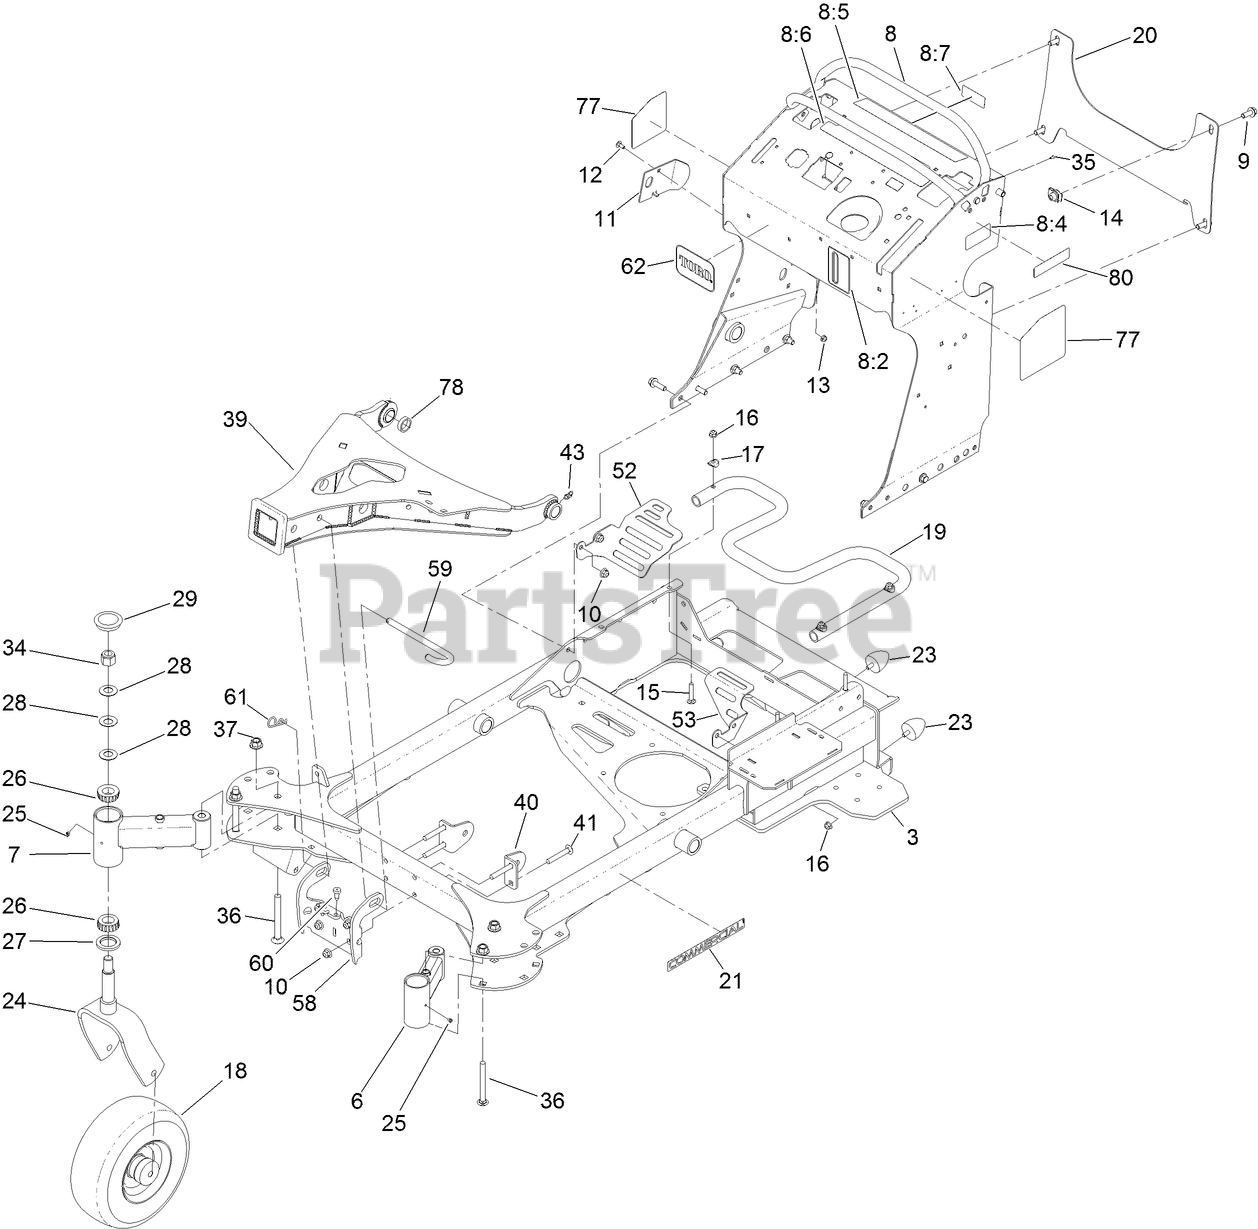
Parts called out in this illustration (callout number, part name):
6	TUBE CASTOR SHORT
7	TUBE CASTOR LONG
8	TOWER DECAL ASM
8:2	DECAL-LEVEL, OIL
8:4	DECAL-FILL, FUEL
8:5	DECAL-CAUTION
8:6	DECAL-CONTROLS
8:7	DECAL-FUSE
9	SCREW-HHF
10	NUT-HF, NI
11	PLATE-STRIKER
12	SCREW-CARR
13	NUT-HF
14	NUT-TINNERMAN
15	BOLT-CAR
16	NUT-HF, NI
17	WASHER
18	WHEEL/TIRE AND BEARING ASM
19	TUBE-MOUNT, FUEL TANK
20	BRACKET-CROSS
21	DECAL-COMMERCIAL
23	BUMPER-RUBBER
24	FORK-CASTER
26	BEARING-ROLLER, TAPERED
27	SEAL-GREASE
28	WASHER-BELLVILLE
29	CAP-GREASE
34	NUT-LOCK, NI
35	RIVET-POP
36	SCREW-CARR
37	NUT-LOCK
40	BRACKET-CYLINDER
41	SCREW-CARR
43	FITTING-GREASE, 90 DEG
52	GUARD-FAN, RH
53	GUARD-FAN, LH
58	BRACKET-LOCK
59	PIN-HITCH
60	BUMPER-RUBBER
61	PIN-HAIR
62	DECAL-LOGO, TORO
77	DECAL SERVICE-MULTIFORCE
78	SPACER
80	DECAL-ARRESTOR, SPARK
